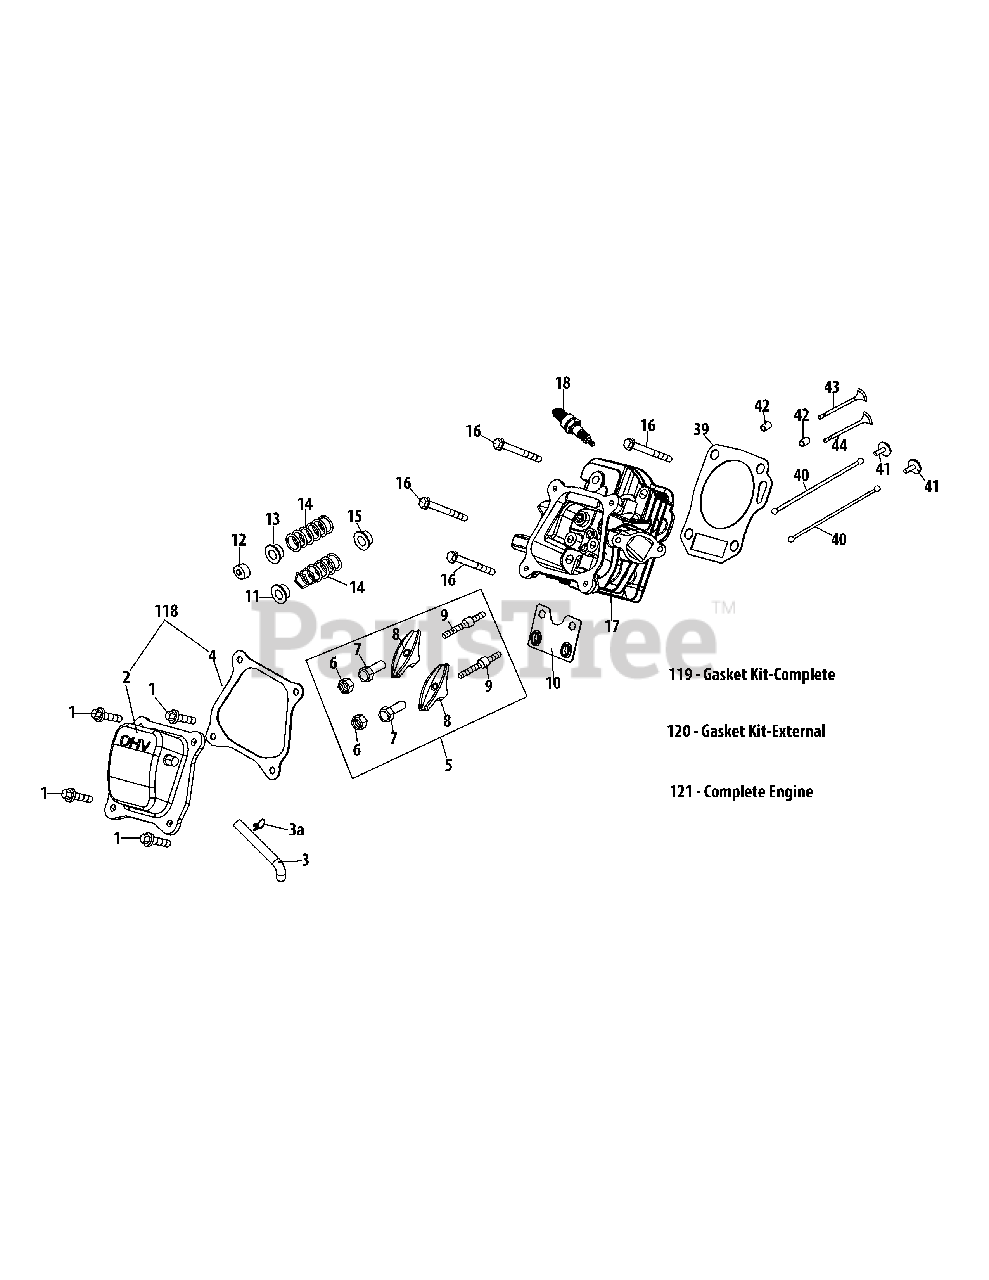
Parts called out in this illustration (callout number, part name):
1	Bolt M6×16
2	Valve Cover
3	Breather Hose
4	Valve Cover Gasket
5	Rocker Arm Assembly
6	Nut, Pivot Locking
7	Adjusting Nut, Valve
8	Rocker Arm
9	Bolt, Pivot
10	Push Rod Guide
11	Valve Spring Retainer (Intake)
12	Exhaust Valve Adjuster
13	Valve Spring Retainer (Exhaust)
14	Valve Spring
15	Valve Seal (Intake)
16	Bolt M8×55
17	Cylinder Head Kit
18	Spark Plug/F6Rtc
39	Cylinder Head Gasket
40	Push Rod Kit
41	Tappet
42	Dowel Pin 10X16
43	Valve Kit
44	Valve Kit
118	Valve Cover Kit
119	Gasket Kit-Complete
120	Gasket Kit-External
121	Complete Engine
